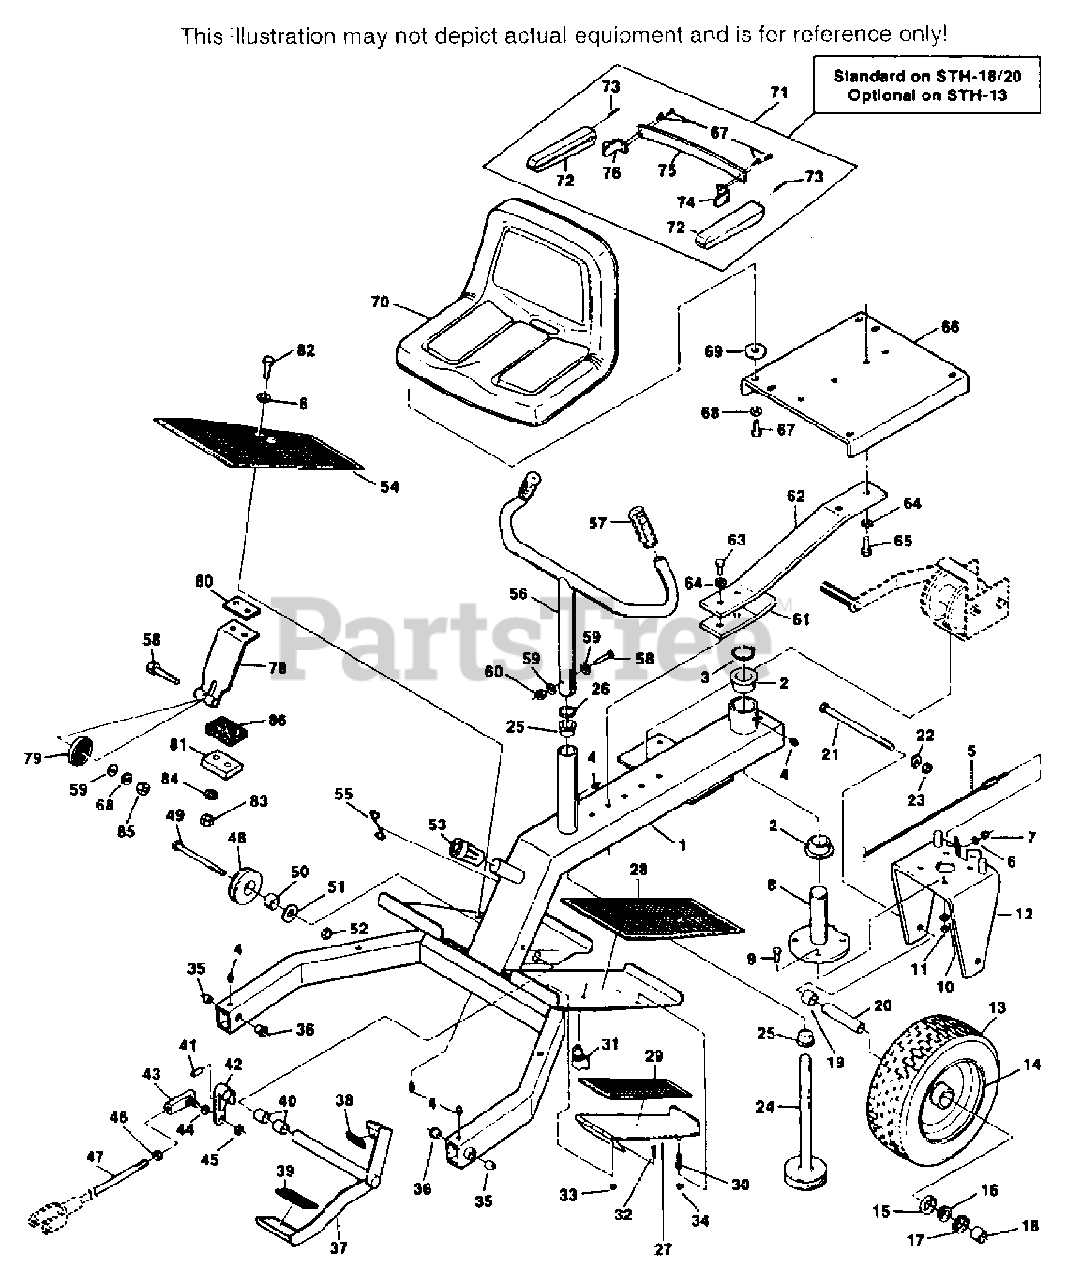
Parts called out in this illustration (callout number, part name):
1	STEERING FRAME(INCL. BUSHINGS & GREASE
2	BRONZE BUSHING
3	RETAINING RING, 1-1/8 EXTERNAL
4	GREASE FITTING
5	CABLE, STEERING
7	HEX NUT, 1/4-28 LOCK
8	REAR WHEEL PIVOT
10	LOCK WASHER, 3/8 SPRING
12	REAR WHEEL YOKE
13	REAR WHEEL ASSEMBLY(INCL. 14, 15, 16, 17)
14	RIM ONLY
15	BEARING CUP
16	BEARING CONE
17	SEAL, GREASE
18	SPACER, REAR WHEEL SHORT
19	SPACER, REAR WHEEL LONG
20	SLEEVE, REAR WHEEL
22	LOCK WASHER, 5/8 SPRING
24	STEERING SHAFT
25	BRONZE BUSHING
26	RETAINING RING, 7/8" EXTERNAL
27	PEDAL, FOOT SAFETY SWITCH
28	PAD, LH
29	PAD, SAFETY PEDAL
30	SPRING, FOOT SAFETY SWITCH
31	SWITCH, FOOT SAFETY
34	HEX NUT, ELASTIC STOP LOCK 1/4-20
35	BRONZE BUSHING
36	BRONZE BUSHING
37	FOOT PEDAL
38	PAD, FOOT PEDAL REVERSE
39	PAD, FOOT PEDAL FORWARD
40	BRONZE BUSHING
41	PIN, DRIVE LOCK, 3/16 X 1-1/4
42	FOOT PEDAL ARM
43	BALL JOINT
47	CONTROL ROD
48	PULLEY, WINCH CABLE
50	BRONZE BUSHING
52	HEX NUT, ELASTIC STOP LOCK 1/2-13
53	BUMPER STOP COVER
54	PAD, RH
55	RETAINER, WINCH CABLE
56	STEERING HANDLE(INCL. 57)
57	GRIP
59	FLAT WASHER, 11/32 X 11/16 X 16 GA.
60	HEX NUT, 5/16-18 CENTER LOCK
61	REINFORCEMENT, SEAT SPRING
62	SEAT SPRING
64	LOCK WASHER, 7/16 SPRING
66	SEAT PLATE
68	LOCK WASHER, 5/16 SPRING
69	FLAT WASHER, 13/32 X 1-1/2 X 7 GA.
70	SEAT ONLY
78	SPRING, NEUTRAL
79	BEARING, NEUTRAL DETENT
80	SHIM, SPRING
81	KEEPER, SPRING
83	HEX NUT, 1/4-20, ELASTIC STOP LOCK NUTS
86	RUBBER BLOCK
